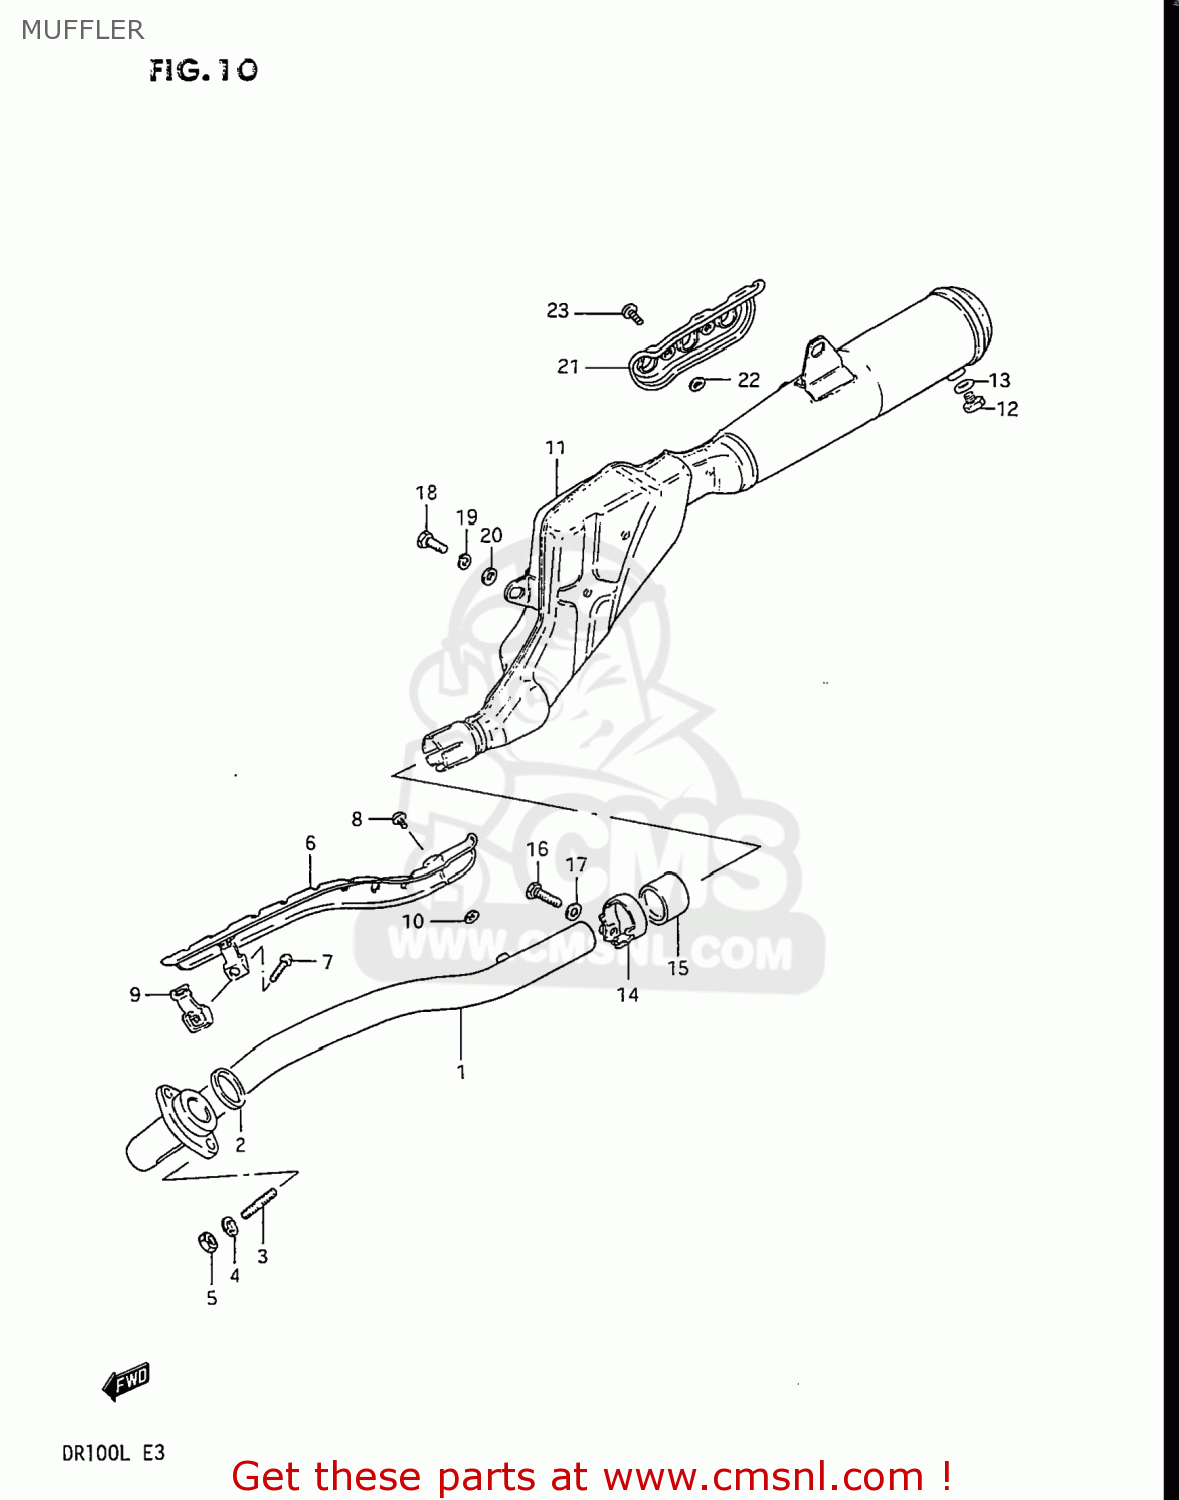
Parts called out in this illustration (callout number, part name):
1	PIPE,EXHAUST
2	GASKET,EXHAUST PIPE (NAS)
3	STUD BOLT L:20
4	WASHER,LOCK
5	NUT
6	COVER,EXHAUST PIPE
7	SCREW 5X20
8	SCREW
9	CLAMP,EXHAUST PIPE COVER
10	GASKET 6.2X12X1.5 (MCA)
11	MUFFLER ASSY
12	PLUG(12X9)
13	GASKET(12.1X16.2X3.7) (NAS)
14	CLAMP,MUFFLER CONNECTOR
15	CONNECTOR,MUFFLER
16	BOLT 8X35
17	WASHER
18	BOLT
19	WASHER,LOCK,8.
20	WASHER
21	COVER,MUFFLER
22	GASKET 6.2X12X1.5 (MCA)
23	SCREW
